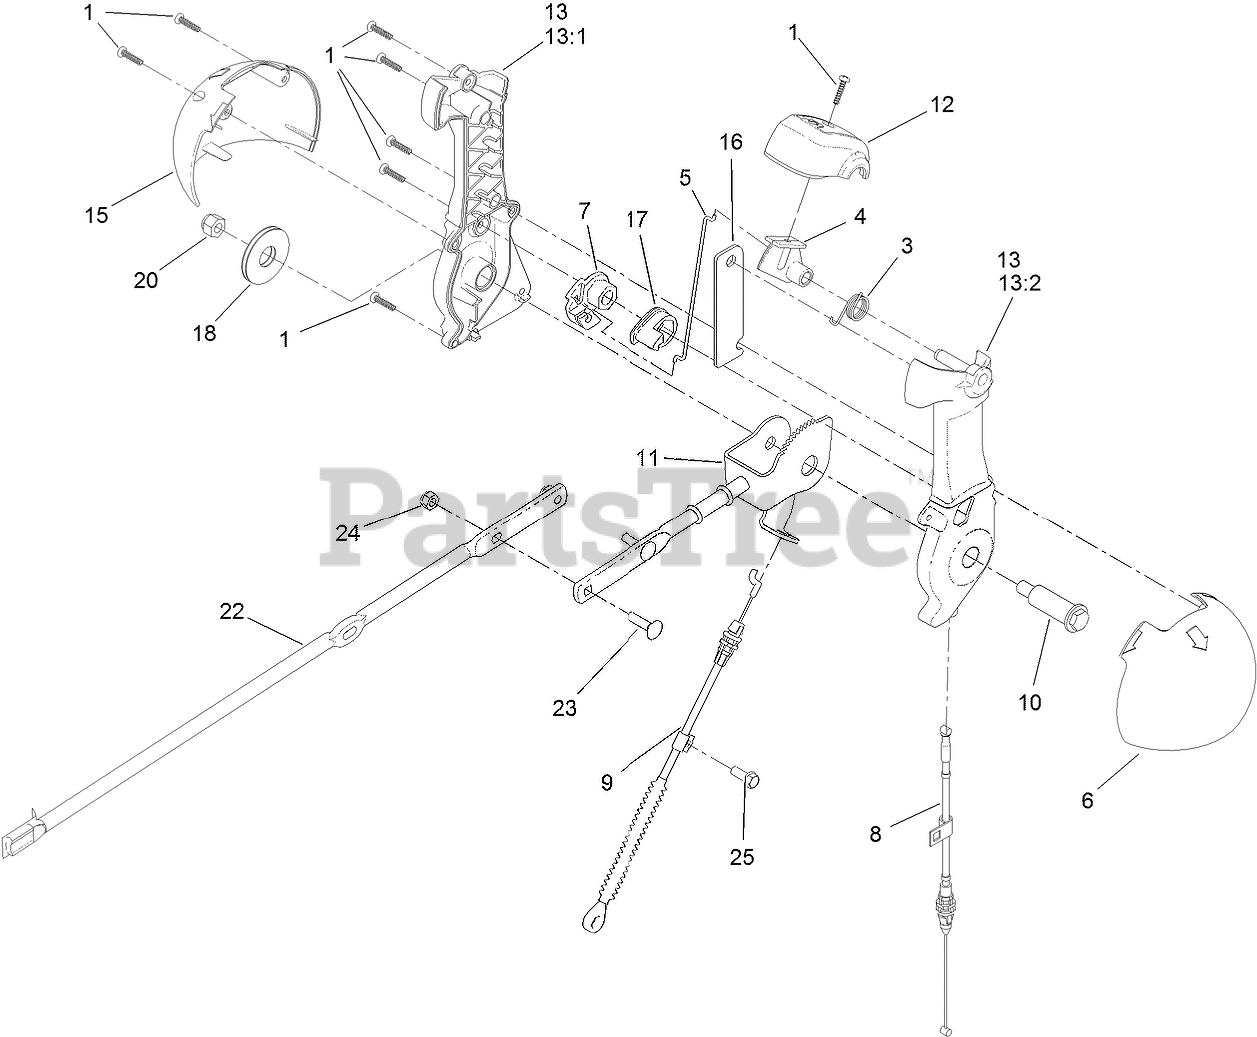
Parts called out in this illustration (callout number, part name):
1	SCREW-PPH
3	SPRING-TORSION
4	TRIGGER-LATCH
5	LINK-LATCH
6	GLOBE-QUICKSTICK, LH
7	LEVER-CABLE, DEFLECTOR
8	CABLE-RELEASE, CHUTE
9	CABLE-CONTROL, DEFLECTOR
10	SCREW-SHOULDER, HWH
11	ROD-CONTROL, CHUTE
12	CAP-LEVER
13	CHUTE CONTROL LEVER ASM
15	GLOBE-QUICKSTICK, RH
16	PLATE-STIFFNER
17	PAWL-LATCH
18	WASHER-FRICTION, COMPOSITE
20	NUT-HEX
22	ROD-CHUTE
23	BOLT-CARR
24	NUT-HEX
25	SCREW-HWH
